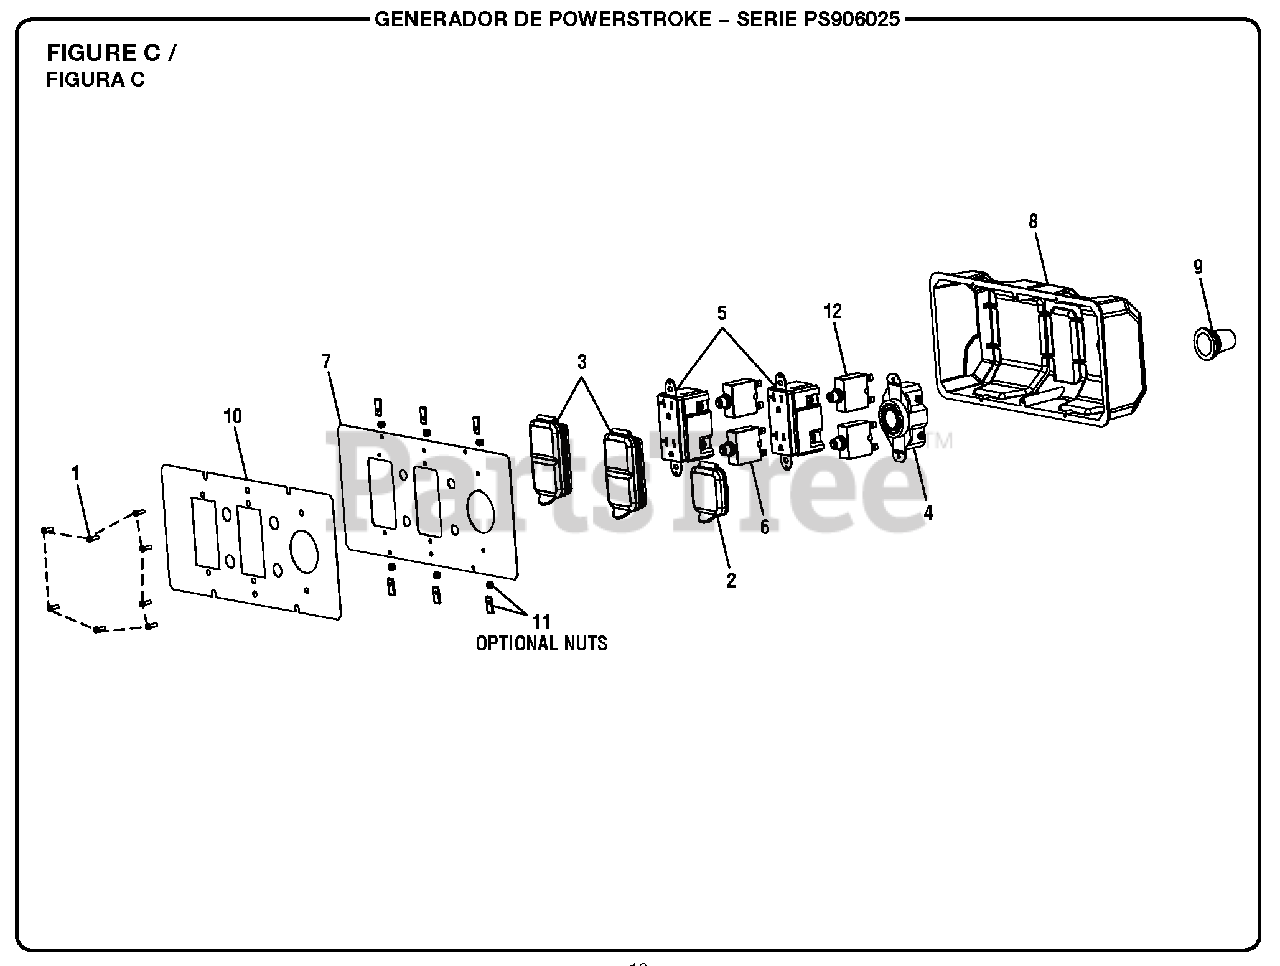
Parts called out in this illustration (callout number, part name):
1	Screw (#6-20 x .38 in.)
2	Outlet Cover (240 Volt)
3	Outlet Cover (120 Volt)
4	Twist Lock Receptacle (240 Volt)
5	Duplex Receptacle (120 Volt)
6	Circuit Breaker (20 Amp)
7	Front Panel
8	Control Box (Back Panel)
9	Rubber Sleeve
10	Front Panel Label
11	Lock Nut (#6- 32)
12	Circuit Breaker (25 Amp)
